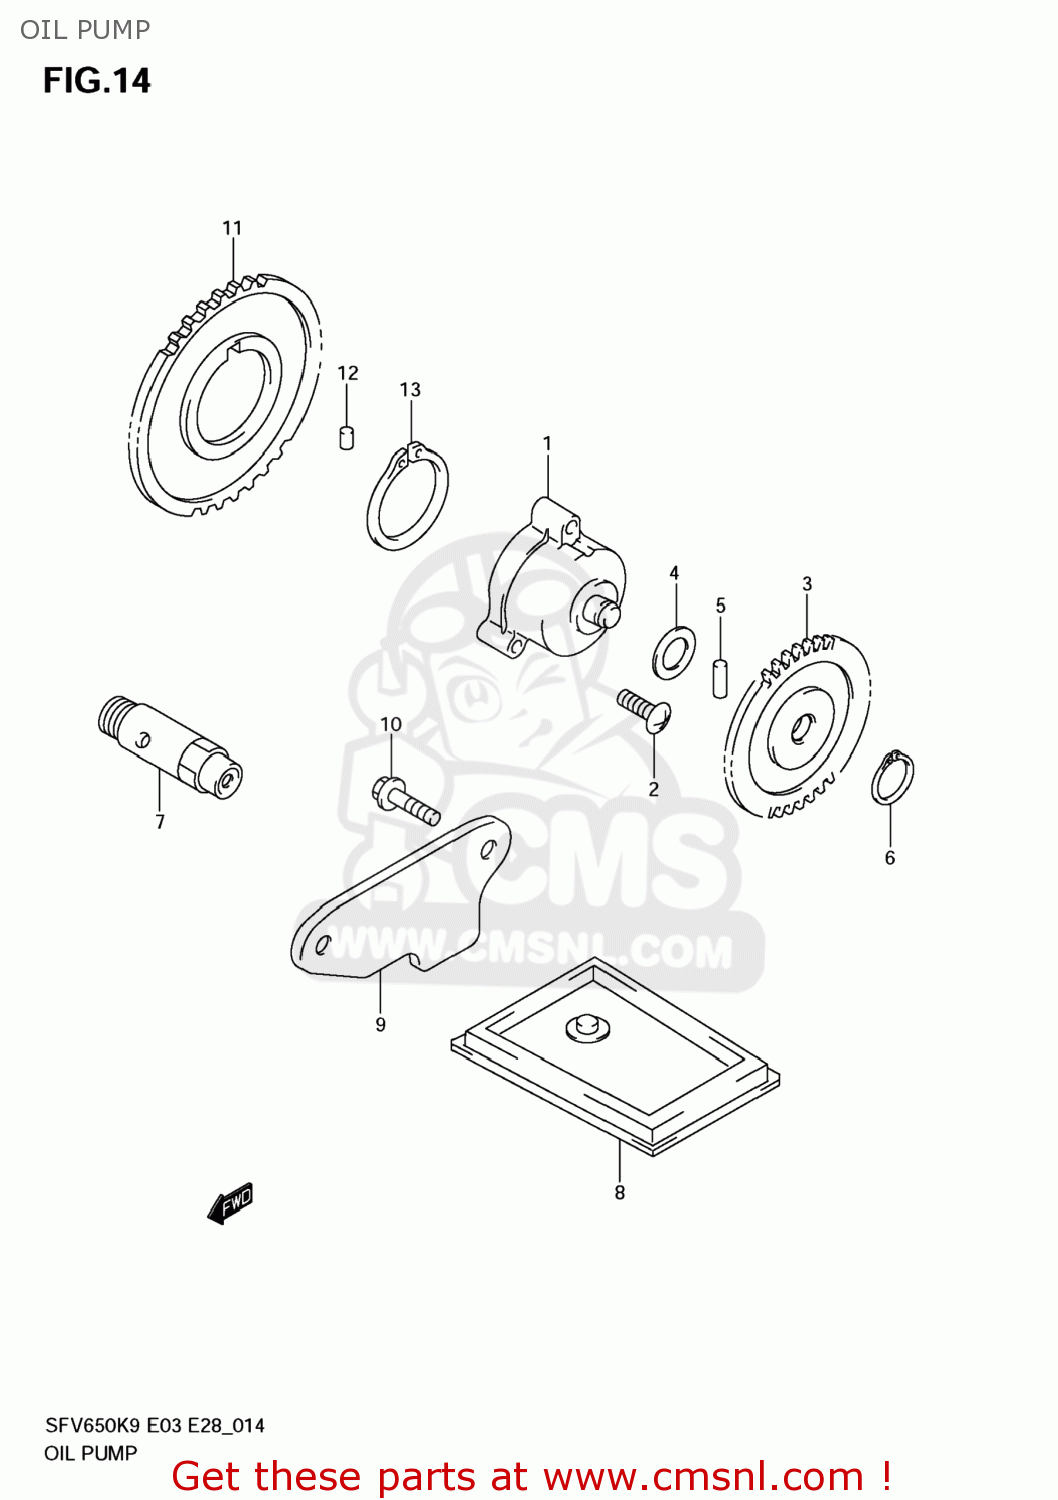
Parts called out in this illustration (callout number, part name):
1	PUMP ASSY,ENGINE OIL
2	BOLT
3	GEAR,ENG OIL PUMP DRIVEN
4	SHIM(10X18X0.5)
5	PIN(4X18.5)
6	CIRCLIP
7	VALVE ASSY,OIL RELIEF
8	STRAINER,ENGINE OIL
9	CAP,OIL STRAINER
10	BOLT
11	GEAR,ENG OIL PUMP DRIVE
12	PIN(6X6)
13	CIRCLIP
